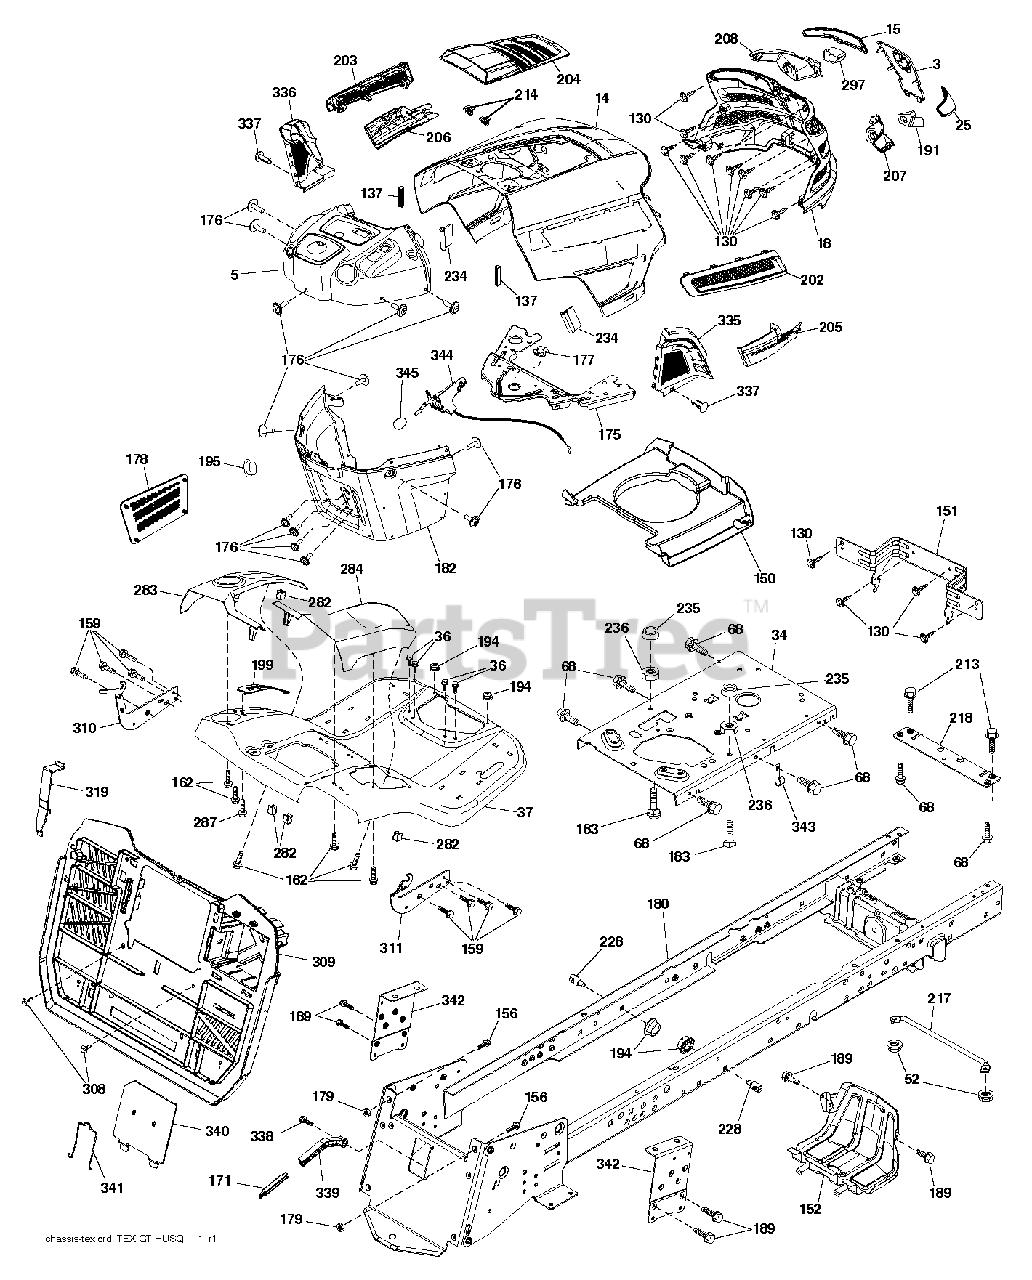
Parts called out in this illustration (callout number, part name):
3	APPLIQUE.SUBASM.GT.HUSQ.II
14	HOOD.ASM.HUSQVARNA.GT.TEX.ORAN
15	LENS.HEADLIGHT.LH.GTII.2011
18	GRILLE.SUBASM.GT.HUSQ.II
25	LENS.HEADLIGHT.RH.GTII.2011
34	PLATE.ENGINE.WELDED.CHASSIS
36	SCREW 5/16"
37	Fender, TEX SRD CRD Front Guards
52	LOCKNUT
68	SCREW LT
130	SCREW.#10 X 0.750.BOS
137	BUMPER DASH
150	AIR.DUCT.GTV2(2.54"RING HEIGHT
151	BRACKET.PIVOT.HOOD.GT.HUSQ.II
152	SHIELD.BROWNING.PNT.GT.V2
159	SCREW, 3/8-16X3/4
162	SCREW.HI-LO.CONSOLE
171	EXTENSION.BAGGER.FULL.
175	PLATE.CROSSMEMBER.HUSQ
176	SCREW.#10-24X5/8.RN.QU
177	BUSHING, STEERING
178	CARGO.ASM.NET.TXGT.W/C
182	DASH DASH LOWER
183	BOLT.5/16-18X1-1/4 FULL THD
189	SCREW
191	INSERT.REFLECTIVE.RH.HUSQ.GTII
194	NUT LOCK HEX FLANGE 5/16-18
195	PLUG.HOLE.DASH.LOWER.12V.BLK
199	PLATE DECK LIFT
202	VENT.SIDE.RH.GT.HUSQ.II.
203	VENT.SIDE.LH.GT.HUSQ.II.498
205	SIDE.TRIM.RH.GT.HUSQ.II
206	SIDE.TRIM.LH.GT.HUSQ.II.GRAY
207	BEZEL LIGHT.RH.GT.II.MYLAR
208	BEZEL LIGHT.LH.GT.II.MYLAR
213	BOLT
214	CLIP.RETAINER.TINNER.
217	ROD.PIVOT.HOOD
218	X-PIECE.HOOD.STOP.NON/
228	STUD.FASTNER.W/ANTI-ROTATE
234	BUMPER.HOOD.TEX.HUSQVARNA
235	SPACER FENDER
236	NUT.CENTERLOCK.5/16-
282	CLIP.RETAINER.CONSOLE.LT.HUSQ
283	CONSL.DECKLIFT.LH.SRD.TEX.CRD
284	CONSL.SHFT.PEDAL.RH.SRD.TEXCRD
287	SCREW 1/4X20
297	INSERT.REFLECTIVE.LH.HUSQ.GTII
308	BOLT, 5/16-18 X 1 3/4
319	BRACKET.ACTUATOR.BAGGER.SRD
335	COVER.RH.CLOSE.OUT.BLACK
336	COVER.LH.CLOSE.OUT
337	CLIP.XMAS.TREE.ITW.2622-00
338	BOLT BOLT SHOULDER
339	LEVER.BAGGER.FULL.TEX.
340	DOOR.PNT.BATTERY.TRY.TEX.CRD.
341	LATCH
342	SUPPORT SUPPORT FENDER
343	CLIP CLIP
344	CONTROL.EZ.MULCH.TEX/CRD
345	RP KNOB.OVAL.TAPERED.3/8-16BLK
